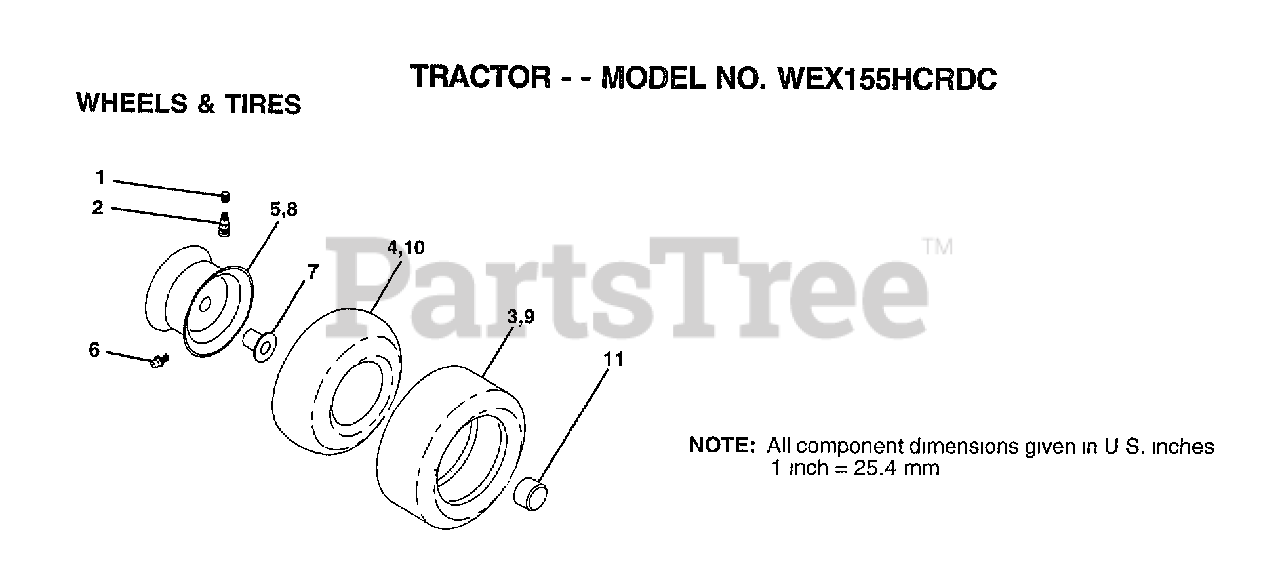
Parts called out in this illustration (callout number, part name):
1	VALVE CAP
2	VALVE STEM LT
4	TUBE.5.3/4.5/6
5	"RIM ASM 6"" FRT"
6	FITTING LT
7	"FLANGE, BEARING"
8	"RIM AS 8"" REAR"
9	TIRE.20X8-8
10	TUBE.18X9.5-8
11	HUB CAP
